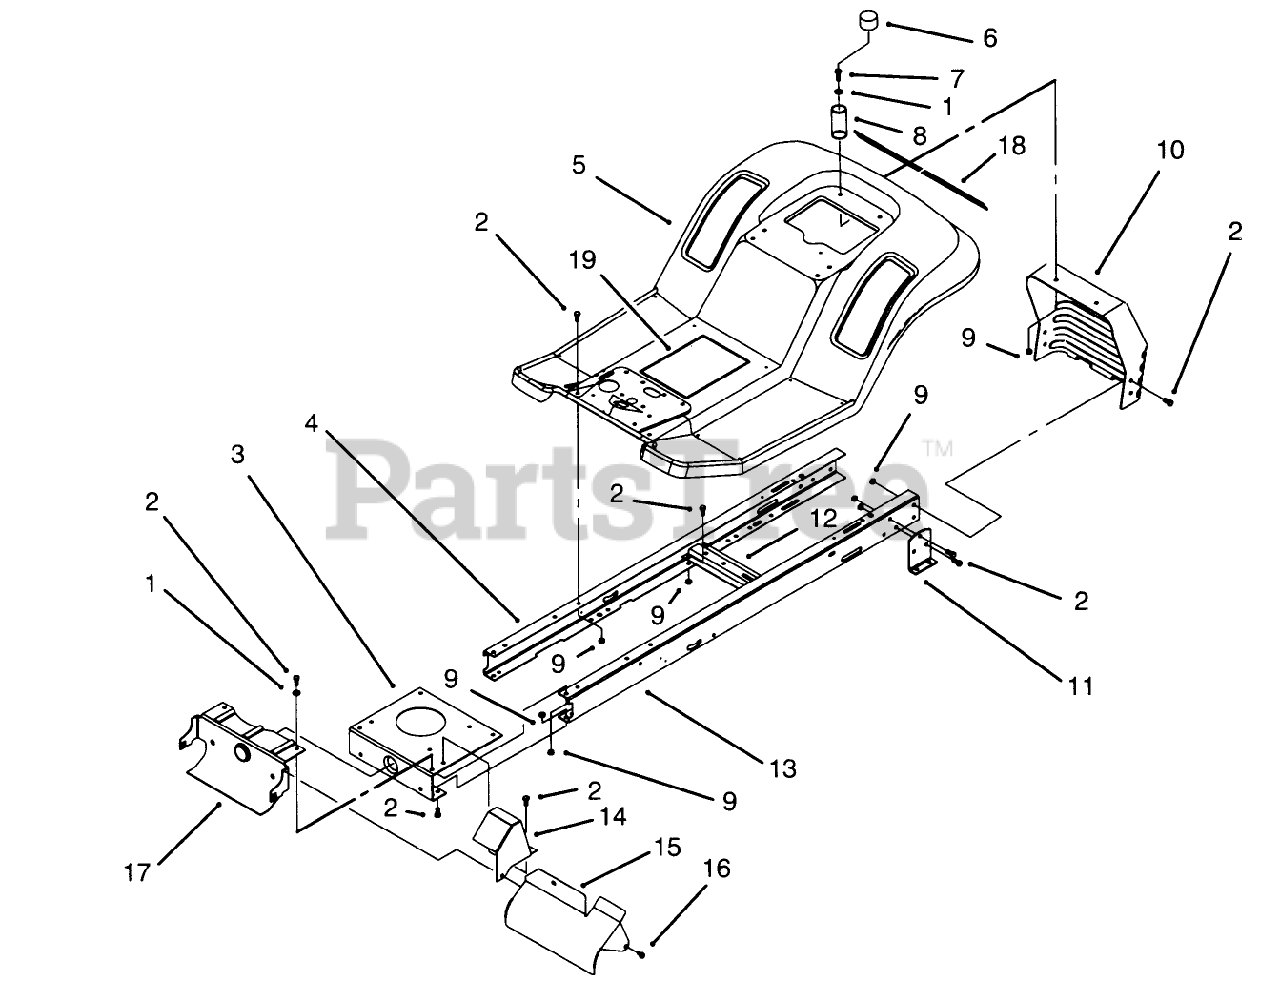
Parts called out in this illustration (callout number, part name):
1	WASHER-PLAIN
2	SCREW-HH
5	BODY-REAR
6	CAP-PROTECTOR
7	SCREW-HH
8	SPRING-COMPRESSION
9	NUT-LOCK, NI
16	SCREW-HWHTF
18	DECAL - REAR BODY
